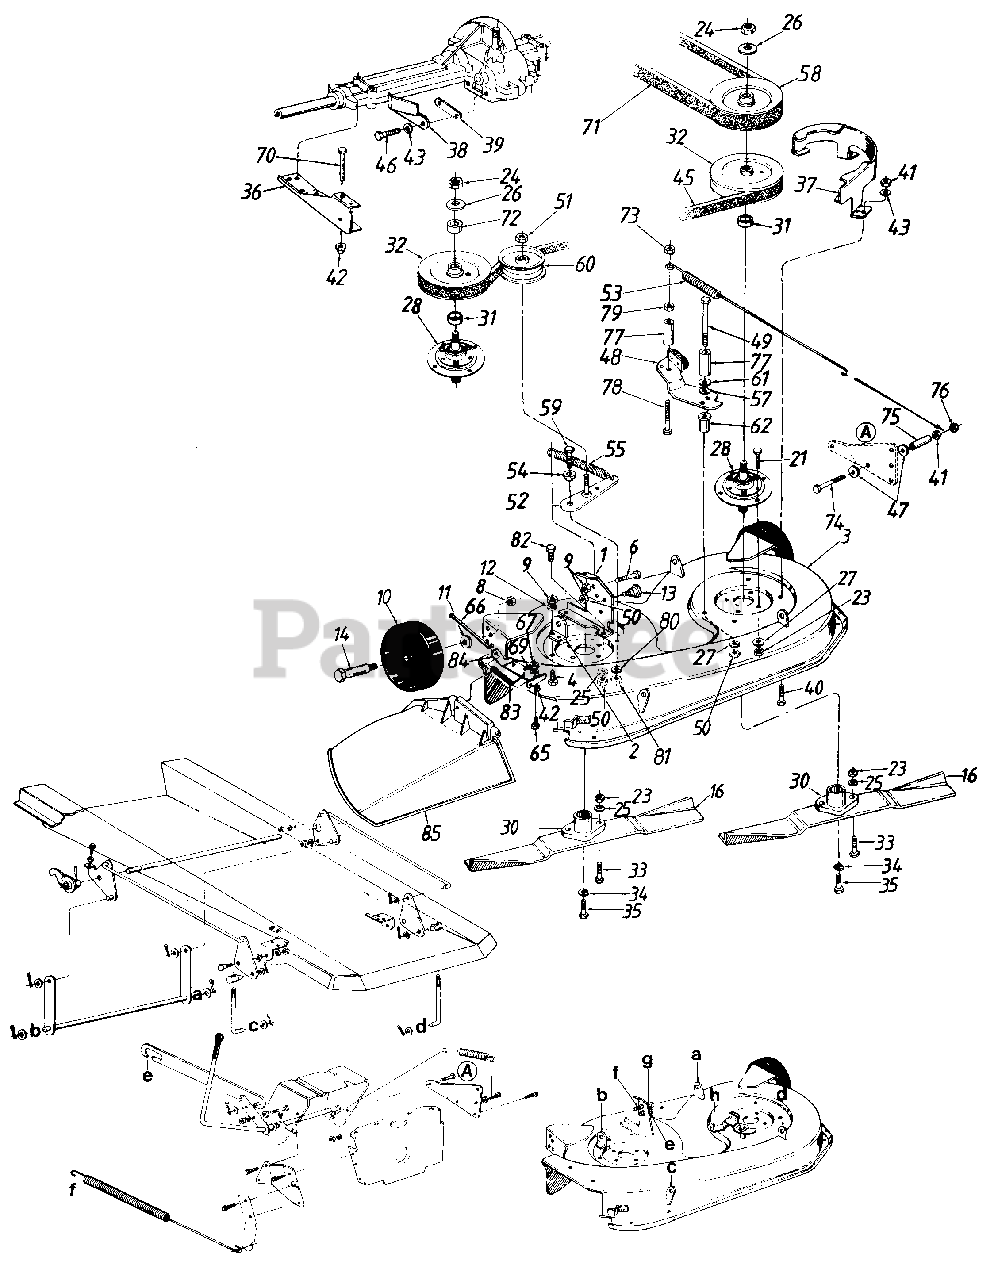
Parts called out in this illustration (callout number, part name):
1	Deck Disengagement Brkt.
2	Rear Deck Brkt.-R.H.
3	38" Deck Ass'y.
4	Hex Bolt 1/4-20 x .62" Lg.
6	Hex Wash. Hd. Scr. 1/4-20 x 1.5" Lg.
8	Hex L-Nut 3/8-16 Thd.
9	Hex Nut 1/4-20 Thd.
10	Deck Wheel
11	Bell-Wash 380 I.D. x .88
12	L-Wash 1/4 I.D.
13	Shld. Bolt .500 Dia. x .215" Lg.
14	Shld. Bolt .498 Dia. x 1.53" Lg.
16	High Lift Blade
21	Hex Bolt 5/16-24 x .75" Lg.
23	Hex Nut 5/16-24 Thd.
24	Hex Jam Nut 5/8-18 Thd.
25	L-Wash. 5/16" I.D.
26	L-Wash. 5/8" I.D.
27	Bell-Wash. .345 I.D. x .88
28	Blade Spindle Ass'y. Comp.
30	Blade Adapter
32	5" Dia. Pulley (1" Hub)
33	Hex Bolt 5/16-24 x 1.0" Lg. (Special)
34	L-Wash. 3/8" I.D. H.D.
35	Hex Bolt 3/8-24 x 1.0" Lg.
39	Belt Guard Spacer
40	Hex Bolt 1/4-20 x .62" Lg.
41	Hex Nut 1/4-20 Thd.
42	Cap Speed Nut 1/4" Rod
43	L-Wash. 1/4" I.D.
45	V-Belt
46	Hex Bolt 1/4-20 x .85" Lg.
47	Fl-Wash. 1/4" I.D.
48	Deck Brake Brkt. Ass'y.
49	Hex Bolt 5/16-18 x 3.25" Lg.
50	Hex Nut 5/16-18 Thd.
51	Hex L-Nut 3/8-24 Thd.
52	Idler Brkt. Ass'y.
53	Extension Spring 17.75" Lg.
54	Shoulder Spacer .625" I.D.
55	Extension Spring 73/4" Lg.
57	Wave Washer .53" I.D. x .78" O.D.
58	5" Dia. Pulley (3/4" Hub)
59	Hex Bolt 3/8-16 x 1" Lg.
60	Flat Idler Pulley
61	Shld. Spacer .51" I.D. x .27" Lg.
62	Spacer .31" I.D. x 1.46" Lg.
65	Truss-Mach. Scr. 1/4-20 x .75" Lg.
66	Hinge Pin 1/4" Dia. x 6.75" Lg.
67	Hex Nut 1/4-20 Thd.
69	Bell-Wash. 1/4" I.D.
70	Pin .25" Dia. x 2.5" Lg.
71	V-Belt
73	Hex L-Nut 1/4-28 Thd.
74	Hex Bolt 1/4-20 x 2.5" Lg.
75	Spacer 1/4" I.D. x 318" O.D.
76	Hex L-Nut 1/4-20 Thd.
77	Spacer 5/16" I.D. x 1/2" O.D.
78	Hex Bolt 1/4-28 x 1.75" Lg.*
79	Hex Nut 1/4-28 Thd.
80	L-Wash. 3/8" I.D.*
81	Hex Nut 3/8-16 Thd.
82	Hex Bolt 5/16-18 x .75" Lg.
83	Torsion Spring
84	Hinge Mtg. Brkt.
85	Chute Ass'y. Comp.
